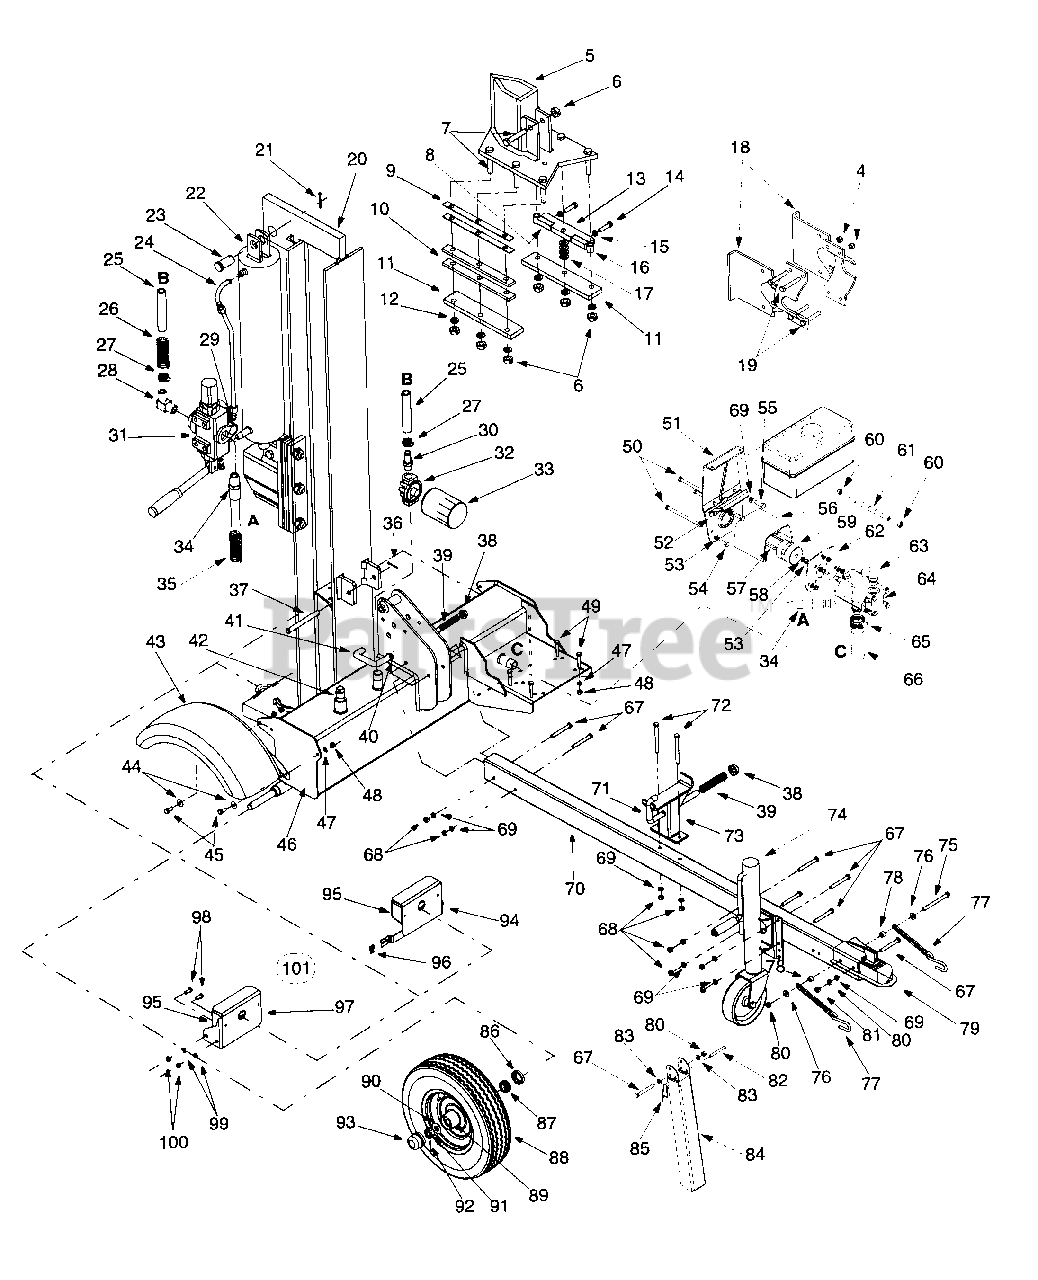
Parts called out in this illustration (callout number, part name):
4	Hex Nut 3/8-16 Thd.
6	Lock Nut 1/2-20
7	Hex Cap Screw 1/2-20 x 2.75
12	Lock Washer 1/2
14	Hex Cap Screw 3/8-24 x 1.5
15	Hex Jam Nut 3/8-24
16	Spacer
17	Flat Washer .531 x .93 x .090
24	Hydraulic Tube
25	Return Hose 3/4" ID x 44" Lg
26	Hose Guards
27	Hose Clamp 5/8"
28	Return Elbow
29	90 Degree Solid Male Adapter
30	3/4" Hose Adapter
32	Filter Housing
33	Oil Filter
34	High Pressure Hydraulic Hose
35	Hose Guards
36	Cotter Pin 1/8" Dia
37	Hinge Pin 1/2 x 4.8" Lg.
38	Push Cap
39	Comp. Spring 4" Lg.
40	Flat Washer .635 ID x .93 OD
41	Locking Rod
42	Pipe Plug
45	Hex Cap Screw 5/16-24 x .75
48	Hex Nut 5/16-24
49	Hex Cap Screw 5/16-24 x 1.75
50	Hex Cap Screw 5/16-24 x 5.25
51	Fuel Tank Mounting Bracket
52	Fuel Tank Support Bracket
53	Lock Washer 5/16
54	Hex Cap Screw 5/16-24 x 1.0
55	Hex Cap Screw 3/8-16 x 1.0
56	Shoulder Spacer
57	Key
58	Hex Nut 5/16
59	Flex Coupling
60	Hose Clamp
61	Fuel Line Hose
63	Adapter 7/8-14
64	Pump (16 gpm)
65	Hose Clamp
66	Suction Hose
67	Hex Cap Screw 3/8-16 x 3.0
68	Hex Nut 3/8-16
69	Lock Washer 3/8
71	Locking Rod
72	Hex Cap Screw 3/8-16 x 4.0
75	Hex Cap Screw 3/8-16 x 4.25
76	Flat Washer .385 ID x .870 OD
77	Chain
78	Spacer
79	Hitch Coupler
80	Lock Nut 3/8-16
81	Hex Jam Nut 3/8-16
82	Clevis Pin
83	Flat Washer
86	Bearing Seal Only
87	Bearing Cone
88	Wheel Asm Comp - Gray
89	Bearing Cup
90	Flat Washer .76" ID x 1.5" OD
91	Slotted Nut 3/4-16
92	Cotter Pin 5/32" x 1-1/4" Lg.
93	Hub Cap
96	Nut 1/4-20
99	Lock Washer 5/16
100	Hex Nut 5/16-24
101	Taillight Kit
